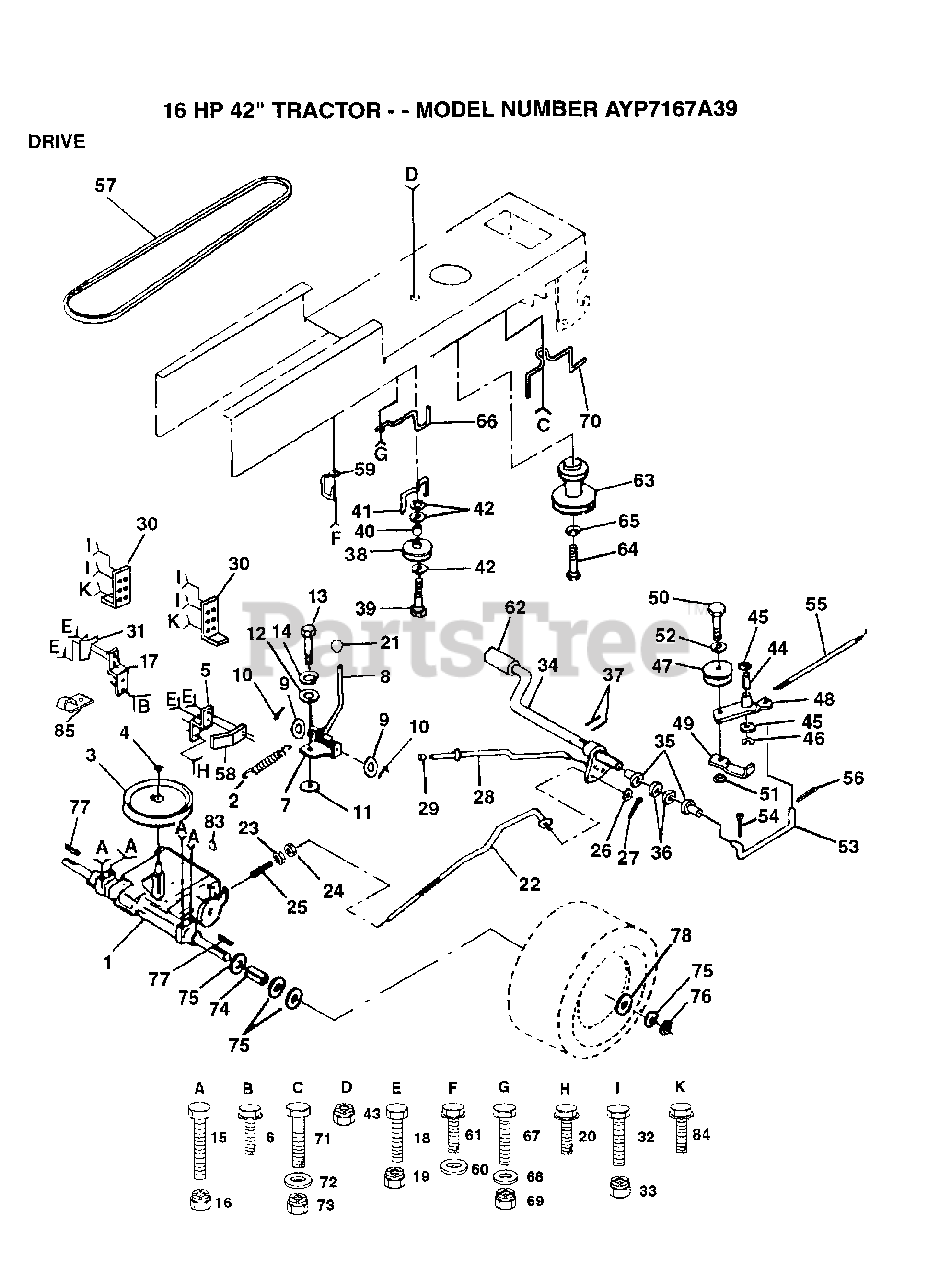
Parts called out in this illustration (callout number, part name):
3	"PULLEY,TRANSAXLE"
4	KLIP RING
5	STRAP TORQUE
6	SCREW
8	SHIFT ROD
9	WASHER
10	PIN COTTER 1/8
11	WASH-SHFT PLT LT
12	WASHER LT
14	LOCKWASHER
15	BOLT
17	STRAP TORQUE
18	BOLT
20	SCREW
21	KNOB T (1/2-HOLE)
22	BRAKE ROD
23	NUT
24	NUT
25	SPRING ROD LT
26	WASHER
27	COTTER PIN
28	BRAKE PARK ROD
29	PLUNGER CAP T
30	TRANSAXLE MTG BKT
31	"KEEPER,BELT LH"
32	BOLT
35	NYLON BEARING
36	WASHER LT
38	PULLEY.IDLER.FLAT
39	BOLT
40	SPACER T
41	BELT KEEPER LT
42	WASHER
44	"LY, BEARING"
45	WASHER LT
46	KLIP RING
48	ARM IDLER
49	RETAIN BELT
52	WASHER
53	"LINK, CLUTCH T"
54	COTTER PIN
55	"SPRING, RETURN LT"
56	COTTER PIN
57	BELT-V
58	"KEEPER,BELT RH"
60	WASHER
61	SCREW
62	PEDAL COVER T
64	BOLT
65	LOCKWASHER
66	KEEPER.BELT.ENG.L
67	BOLT
68	WASHER
70	KEEPER BELT ENG
71	BOLT
72	WASHER
74	SPACER LT
75	WASHER
76	E-RING LT
77	SQUARE KEY
78	WASHER
84	SCREW
85	"CLIP,INSULATOR"
